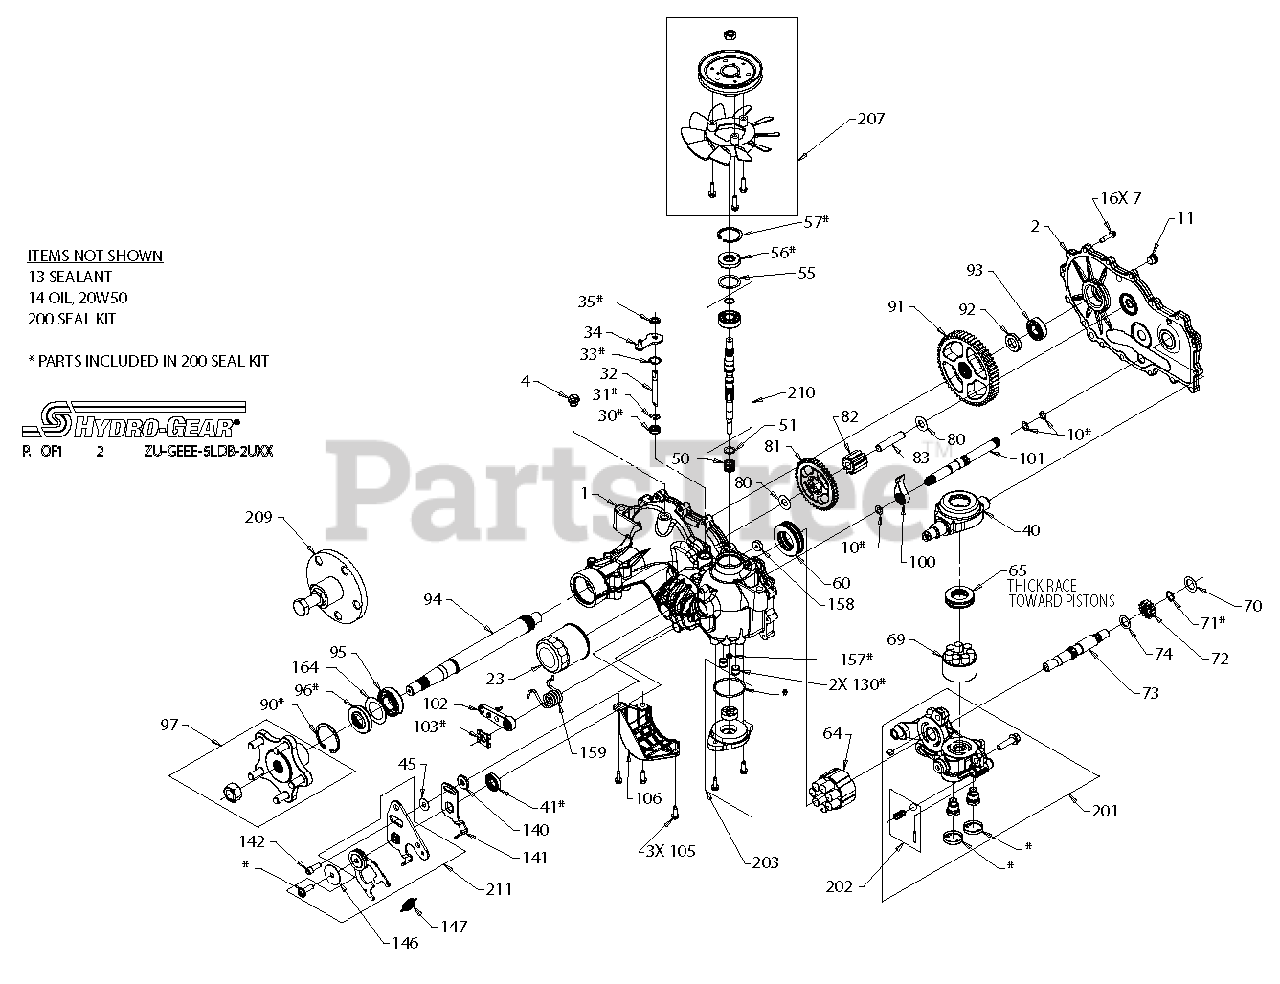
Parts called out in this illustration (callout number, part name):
23	FILTER, OIL
30	SEAL, LIP .375 X .75 X .25
31	RING, RET .375 EXTERNAL
35	RING, RTNG .375 EXT
40	TRUNNION, SWASHPLATE
41	SEAL, LIP 18 X 32 X 7
51	WASHER FLAT .59 X .79 X .04
55	WASHER 1.23 X 1.56 X .04
56	SEAL, LIP 17 X 40 X 7
57	RING, RET 2.06 INT
80	WASHER .5 X 1.0 X .03
95	BRG, BALL 1.0 X .52 X .15 OPEN 6205M
96	SEAL, LIP TC4 1.0 X 2.06 X .38
97	KIT, HUB, 5 BOLT
146	WASHER .343 X 1.500 X .062
147	SPRING, EXTENSION RTN 34 LBS
157	SEAL, LIP .281 X .420 X .16
